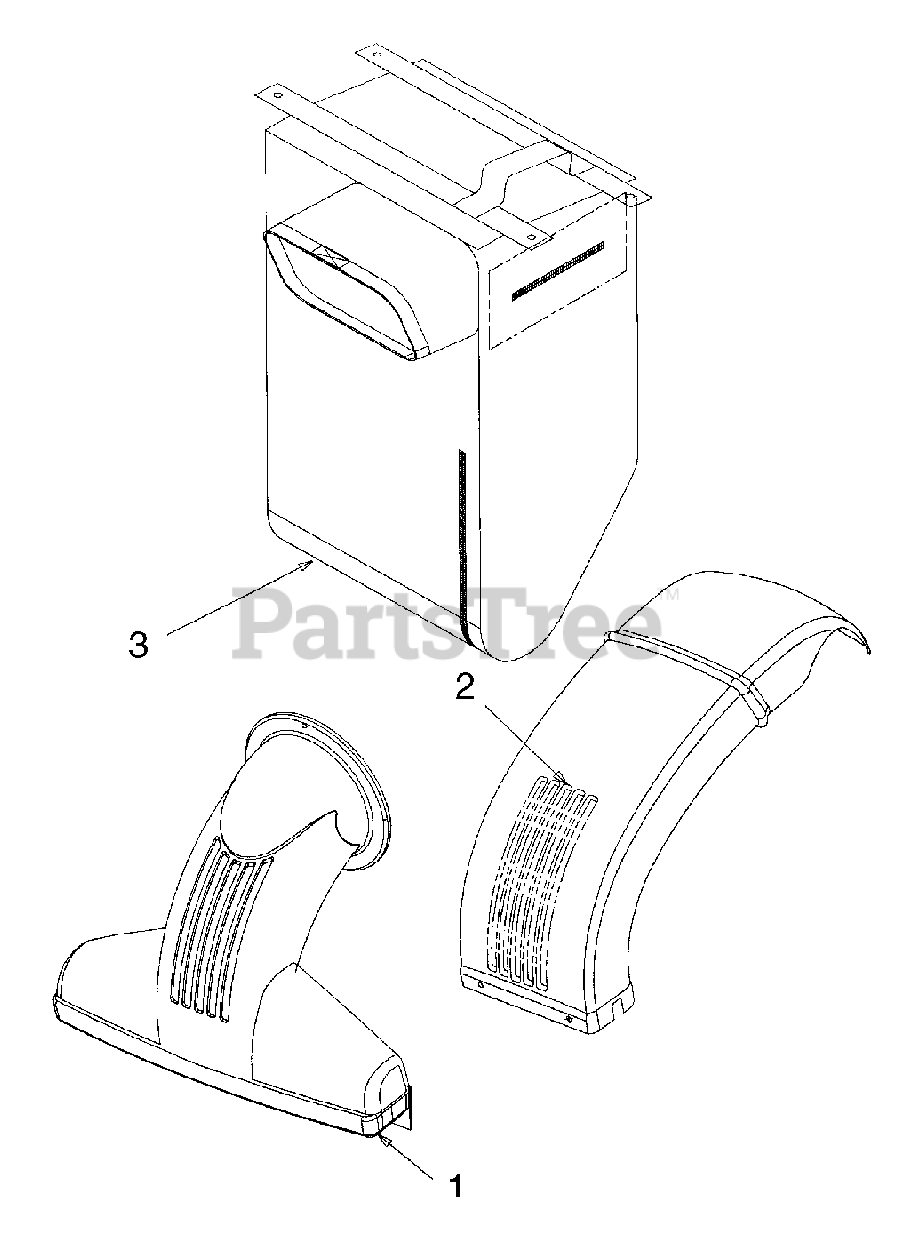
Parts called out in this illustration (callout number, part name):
1	Nozzle Assembly, Vacuum
2	Chute, Discharge
3	Bag, Vacuum
